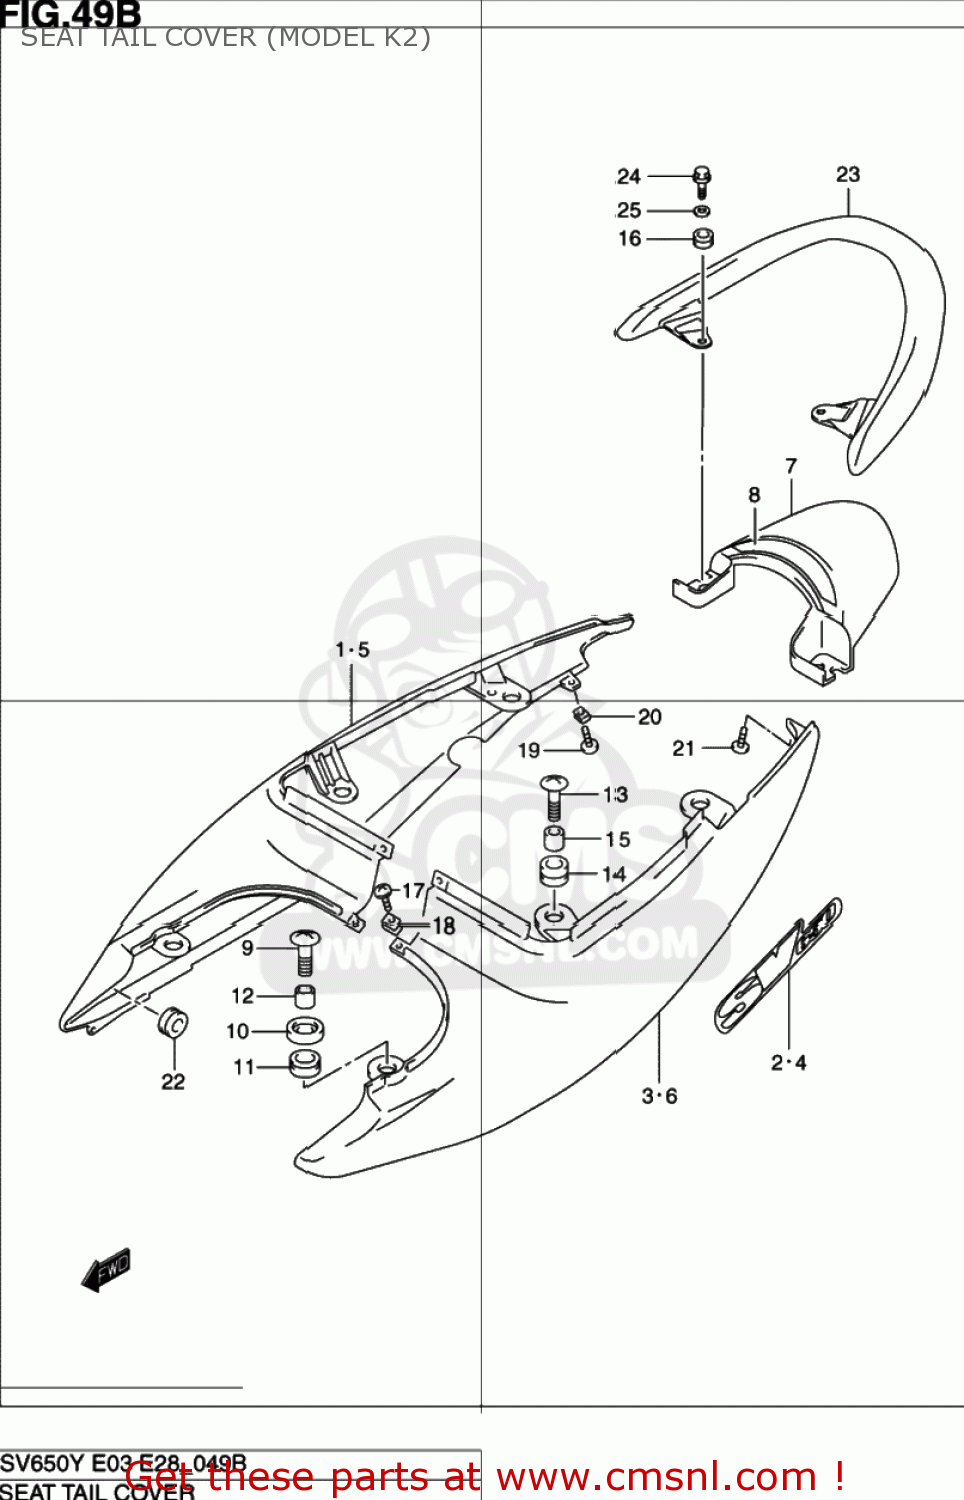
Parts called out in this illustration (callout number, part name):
1	COVER,SEAT TAIL,R
2	EMBLEM,SEAT TAIL COVER
3	COVER,SEAT TAIL,L
4	EMBLEM,SEAT TAIL COVER
5	COVER,SEAT TAIL,R(BLUE)
6	COVER,TAIL,L
7	COVER,SEAT TAIL CTR
8	TAPE,SEAT TAIL COVER CTR
9	SCREW(6X30)
10	CUSHION,SEAT TAIL FR UPR
11	CUSHION,SEAT TAIL COVER FR
12	SPACER(6.5X10X15.7)
13	SCREW(6X20)
14	CUSHION
15	SPACER(6.5X10X9.4)
16	CUSHION,SEAT TAIL COVER RR
17	SCREW
18	NUT
19	SCREW
20	NUT
21	SCREW
22	CUSHION
23	HANDLE,PILLION RIDER(BLACK)
24	BOLT
25	WASHER(8.5X20X2.6)
